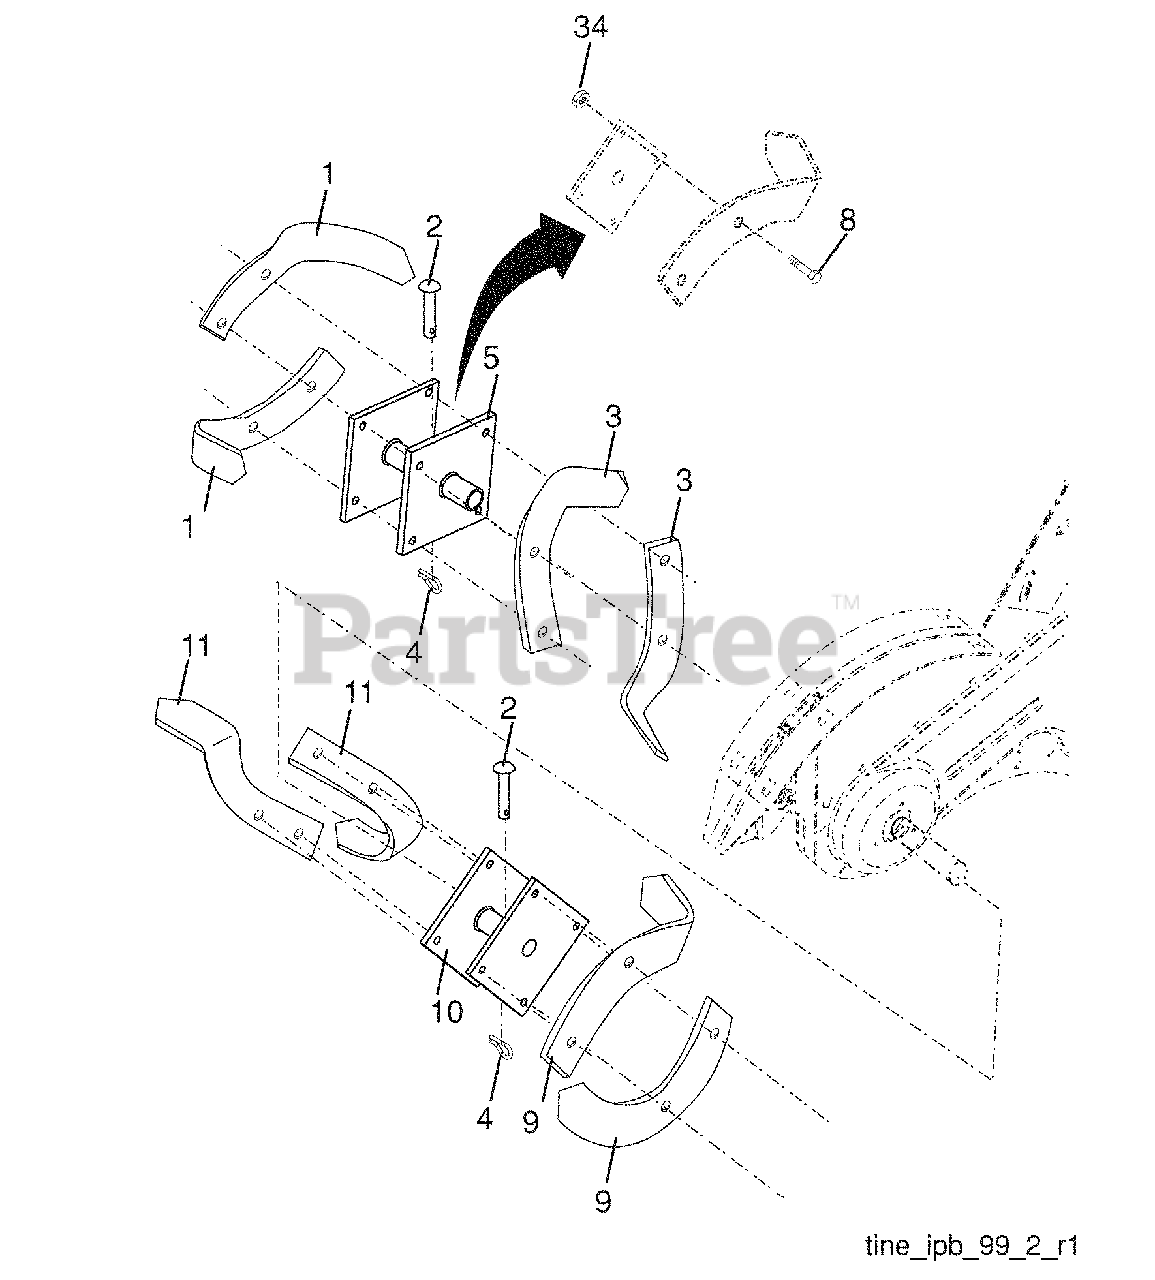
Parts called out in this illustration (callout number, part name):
1	Tine, Outer, L.H.
2	Clevis Pin
3	Tine, Inner, L.H.
4	Retainer, Spring Zinc
5	Assembly, Hub and Plate, L.H.
8	Bolt, Hex 3/8-24 x 1
9	Tine, Outer, R.H.
10	Assembly, Hub and Plate, R.H.
11	Tine, Inner, R.H.
34	Nut Crownlock 3/8-24
